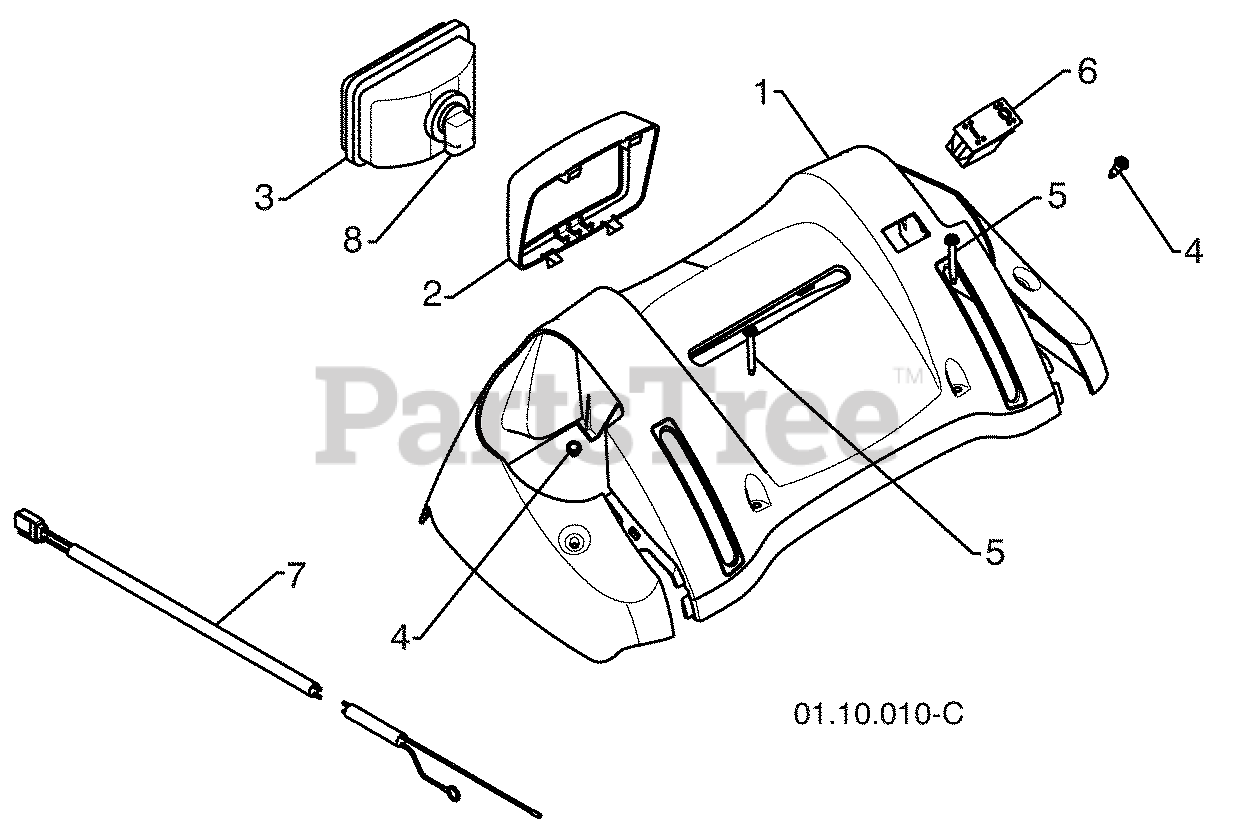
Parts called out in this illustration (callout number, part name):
1	CONSOLE PANEL GRAY
2	HEADLIGHT BEZEL GRAY
3	HALOGEN HEADLIGHT
4	SHOULDER SCREW 10-24 X .625
5	SCREW 10-24 X 1.25
6	GRIP SWITCH
7	WIRE HARNESS
